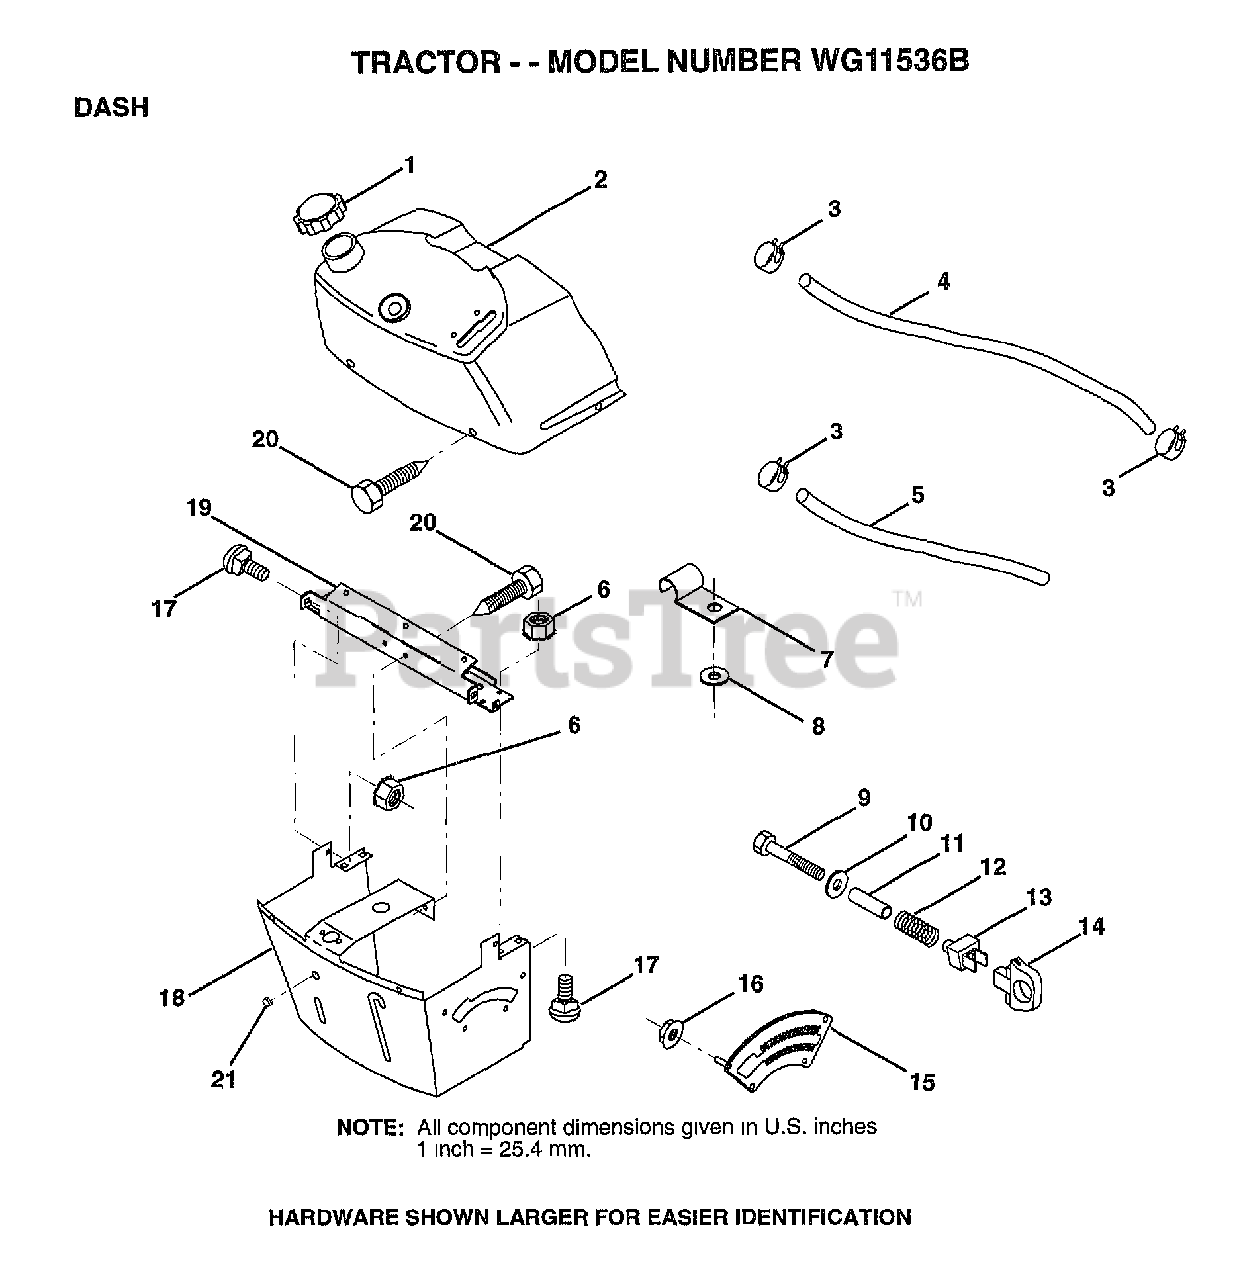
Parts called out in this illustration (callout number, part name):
1	CAP BLK FUEL LR
2	TANK.ASM.DASH.LR
3	HOSE CLAMP
5	FUEL LINE T
6	NUT HXKEP 1/4X20
7	CLIP T
8	WASHER PM
9	BOLT
11	SPACER SPLIT
12	SPRING M
13	"KNOB,HGT RETAINER"
14	KNOB
15	ADJUSTER QUAD
16	NUT
17	BOLT
18	SUPT ASSY DASH
19	CROSS BRACE
20	SCREW.1/4-20X1/2
21	PLUG DOME
